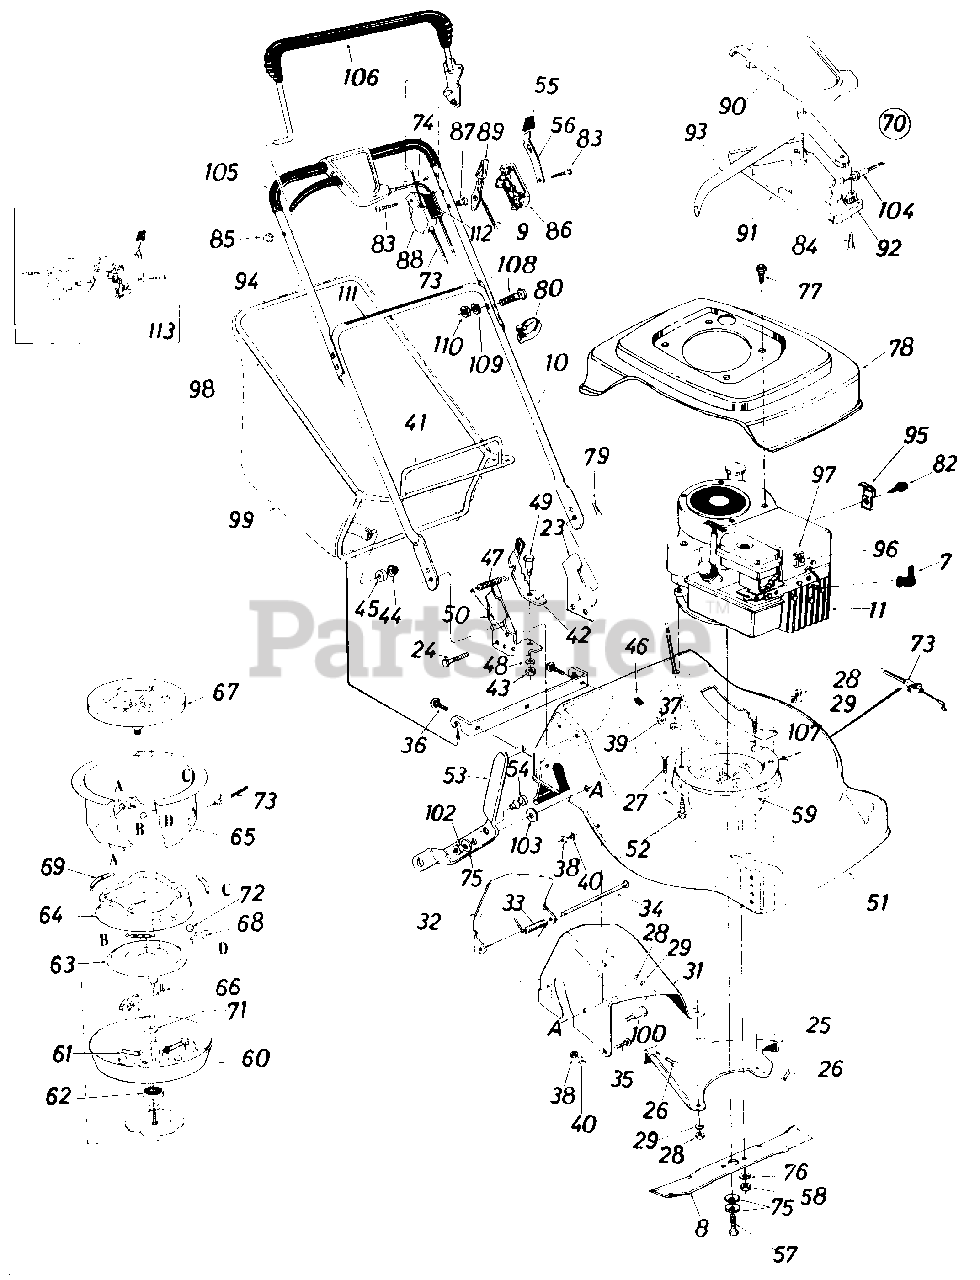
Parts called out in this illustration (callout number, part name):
7	Spark Plug Boot
8	22" Blade
9	Throttle Control Wire - 58"
10	Lower Handle
11	Engine
23	Handle Brkt. Ass'y. - L.H.
24	Hex Wash. Hd. AB-Tap Scr. 1/4" x .62" Lg.
25	Rear Baffle - L.H.
26	Carriage Bolt 1/4-20 x .50" Lg.
27	Hex Bolt 1/4-20 x .88" Lg.
28	Hex Nut 1/4-20 Thd.
29	L-Wash. 1/4" I.D.
31	Rear Chute Baffle Ass'y.
32	Chute Door
33	Torsion Spring
34	Hinge Pin .250" Dia. 7.88" Lg.
35	Carriage Bolt 1/4-20 x .50" Lg.
36	Carriage Bolt 1/4-20 x .75" Lg.
37	Sems Nut 1/4-20 Thd.
38	Hex Nut 1/4-20 Thd.
39	Fl-Wash. .285" I.D. x 1.25" O.D.
40	L-Wash. 1/4" I.D.
43	Hex Nut 5/16-18 Thd.
44	Push Nut 3/8" Rod
45	Plastic Roller
47	Extension Spring .33" O.D. x 1.12" Lg.
48	L-Wash. 5/16" I.D.
49	Shld. Bolt .437" Dia. x .162" Lg.
50	Handle Brkt. Ass'y. - R.H.
51	22" Deck Ass'y.
52	Hex Wash. Hd. TT-Tap Scr. 3/8-16 x 1.0" Lg.
53	Rear Wheel Pivot Brkt. Ass'y.
54	Rubber Bumper
55	Spring Lever Knob
56	Lockout Lever
57	Hex Bolt 3/8-24 x 2.00" Lg. (Grade 8)
58	Hex Nut 3/8-24 Thd. (Grade 8)
59	Blade Brake Clutch Ass'y. Comp.
60	Clutch Blade Housing Ass'y.
61	Compression Spring .35" O.D. x 2.00" Lg.
62	Ball Brg. .669" I.D. x 1.574" O.D. x .47
63	Clutching Cone
64	Brake Cup Cone
65	Clutch Housing
66	Hex TT-Tap L-Scr. 1/4-20 x .75" Lg.
67	Fan Adapter
68	Ball Block
69	Extension Spring .35" O.D. x 1.75" Lg
70	Clutch Control Housing - Comp.
71	Fl-Wash. .690" I.D. x 1.060" O.D.
72	Steel Ball .500" Dia.
73	Blade Clutch Cable - 46"
74	Lock Pin .314" Dia. x 1.70" Lg.
75	Bell-Wash. .44" I.D. x .88" O.D.
76	L-Wash. 3/8" I.D.
77	Hex Wash. Hd. AB-Tap Scr. #8 x .50" Lg
78	Engine Shroud
79	Intern. Cot. Pin 5/16" Dia.
80	Cable Tie
82	Hex AB-Tap Scr. #8 x .38" Lg.
83	Truss Mach. Scr. #12 x 1.50" Lg.
84	Flat "C"-Sunk Hd. Scr. #10 x 1.0" Lg.
85	Cap Speed Nut 5/16" Rod
86	Control Panel Half
87	Control Disc Pin
88	Clutch Panel Half
89	Throttle Control Lever
90	Control Cover Half - Upper
91	Control Cover Half - Lower
92	Cable Mtg. Cap
93	Control Lever
94	Upper Handle
95	Casing Clamp
96	Hex B-Tap Scr. #10 x .38" Lg.
97	Casing Clamp
98	Grass Catcher Upper Frame
99	Grass Catcher Bag
100	Shld. Bolt .500" Dia. x .685" Lg.
103	Bell-Wash. .400" I.D.
104	Drive Clutch Cable - 50"
106	Blade Clutch Control Handle
107	Hex Wash, Hd. Self-Tap Scr. 1/4-20 x 75" Lg
108	Curved Hd. Carr. Bolt 5/16-18 x 1.38
109	L-Wash. 5/16" I.D.
110	Hex Nut 5/16-18 Thd.
111	Instruction Label - Handle
112	Control Label - Throttle
113	Control Housing Comp.
